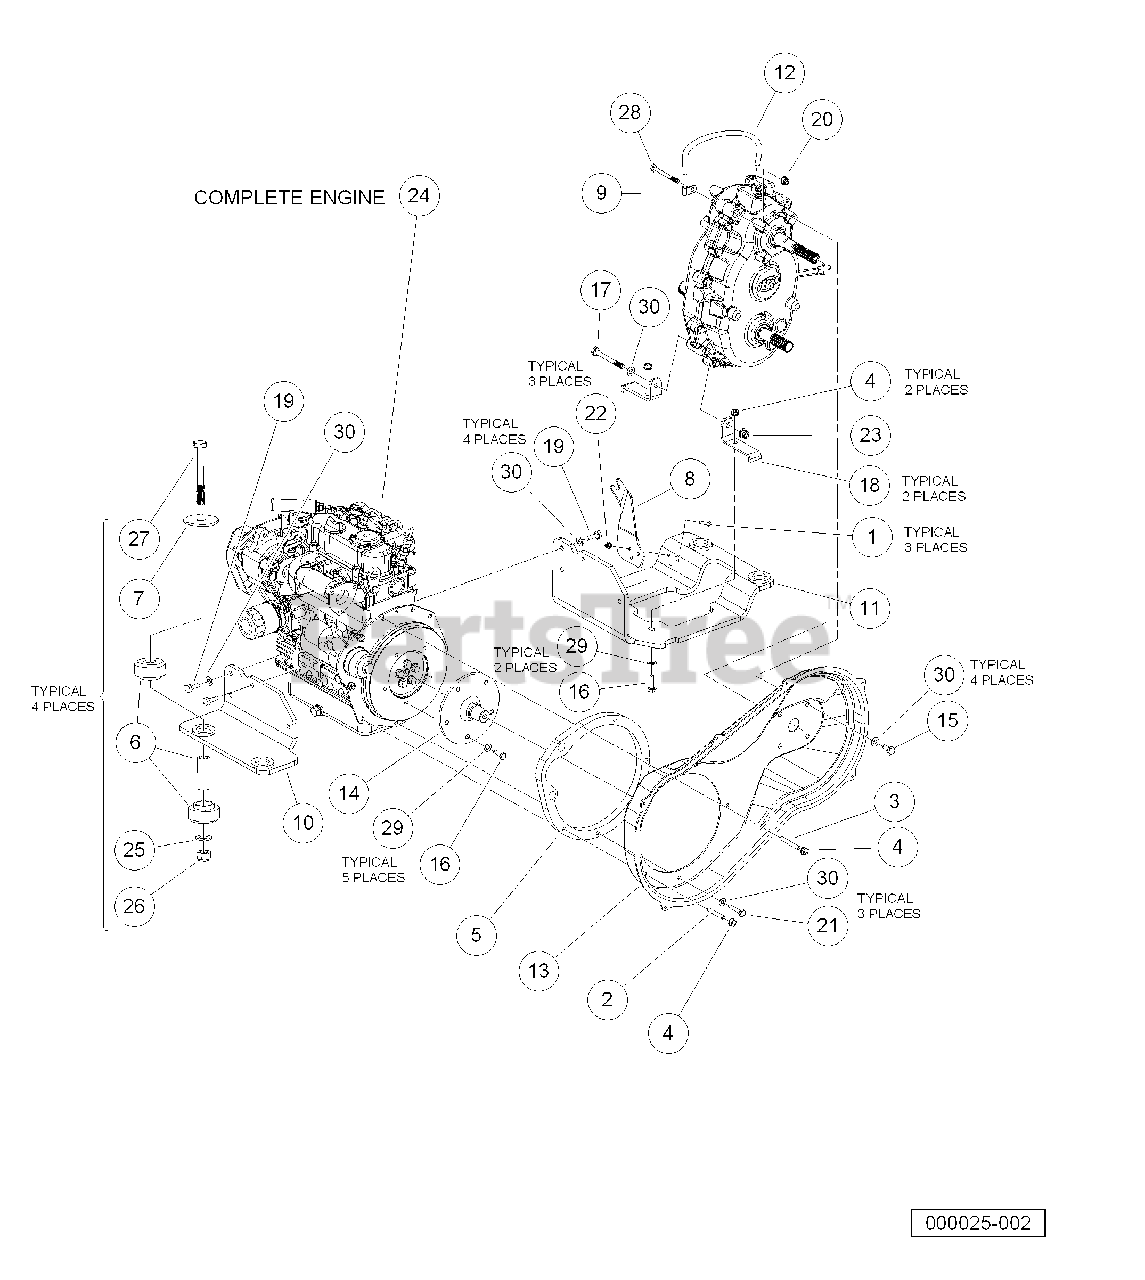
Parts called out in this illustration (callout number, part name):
1	Screw, M6-1.00 X 25mm Hex Cap
2	Stud, M8-1.25 X 50 mm Two-Ended
3	Stud, M8-1.25 X 60mm Two-Ended
4	Nut,m8,all Metal Lock
5	Spacer, Engine, Diesel
6	Isolator Ring and Bushing
7	Washer, Snubbing, Ring N Bush
8	Bracket, FNR Trans Cable
9	P-Clamp, Insulated .312 In
10	Plate, Engine Mounting, Weld, Left-Hand
11	Plate, Engine Mounting, Weld, Right-Hand
12	Hose, Vent, Transmission
13	Cover, CVT Inner, Diesel
14	Shaft, CVT Adapter
15	Bolt, M10 X 1.5 X 20 Loctite
16	Bolt, M8 X 1.25 X 25 Loctite
17	Bolt, M10 X 1.5 X 100 Loctite
18	Bracket, Transmission Mounting
19	Bolt, M10 X 1.25 X 25 Loctite
20	Lock Nut, Flg M8 X 1.25 Nylon
21	Bolt, M8 X 1.25 X 40 with Loctite
22	Nut Flg, M6 X 1.0 Nylon
23	Nut Flg M10 X 1.5 Nylon
24	Engine, Kubota, D722, with Closed Breather, 60a
25	Washer, M12 Hard
26	Locknut, M12x1.75 Nylon Insert
27	Bolt, M12 X 1.75 X 90
28	Bolt, M8 X 1.25 X 80
29	Washer, M8 Hard
30	Washer, M10 Hard
